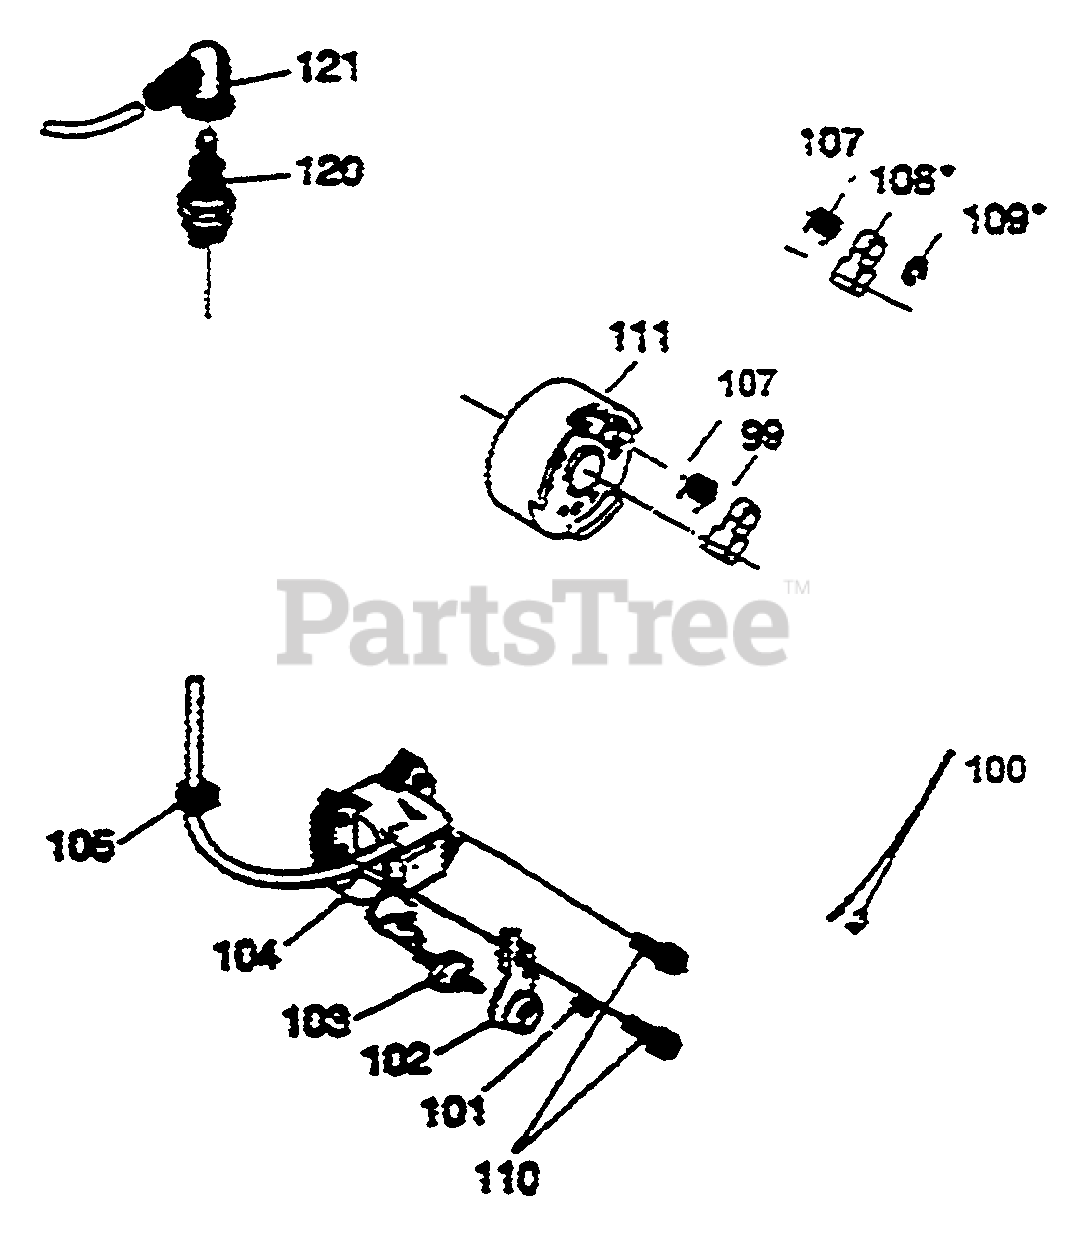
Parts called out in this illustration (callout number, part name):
100	HARNESS, WIRE
103	SWITCH, STOP
104	COIL, IGNITION
107	SPRING, RETURN
109	SNAP RING
110	BOLT & WASHER
120	SPARK PLUG
121	CAP, PLUG
